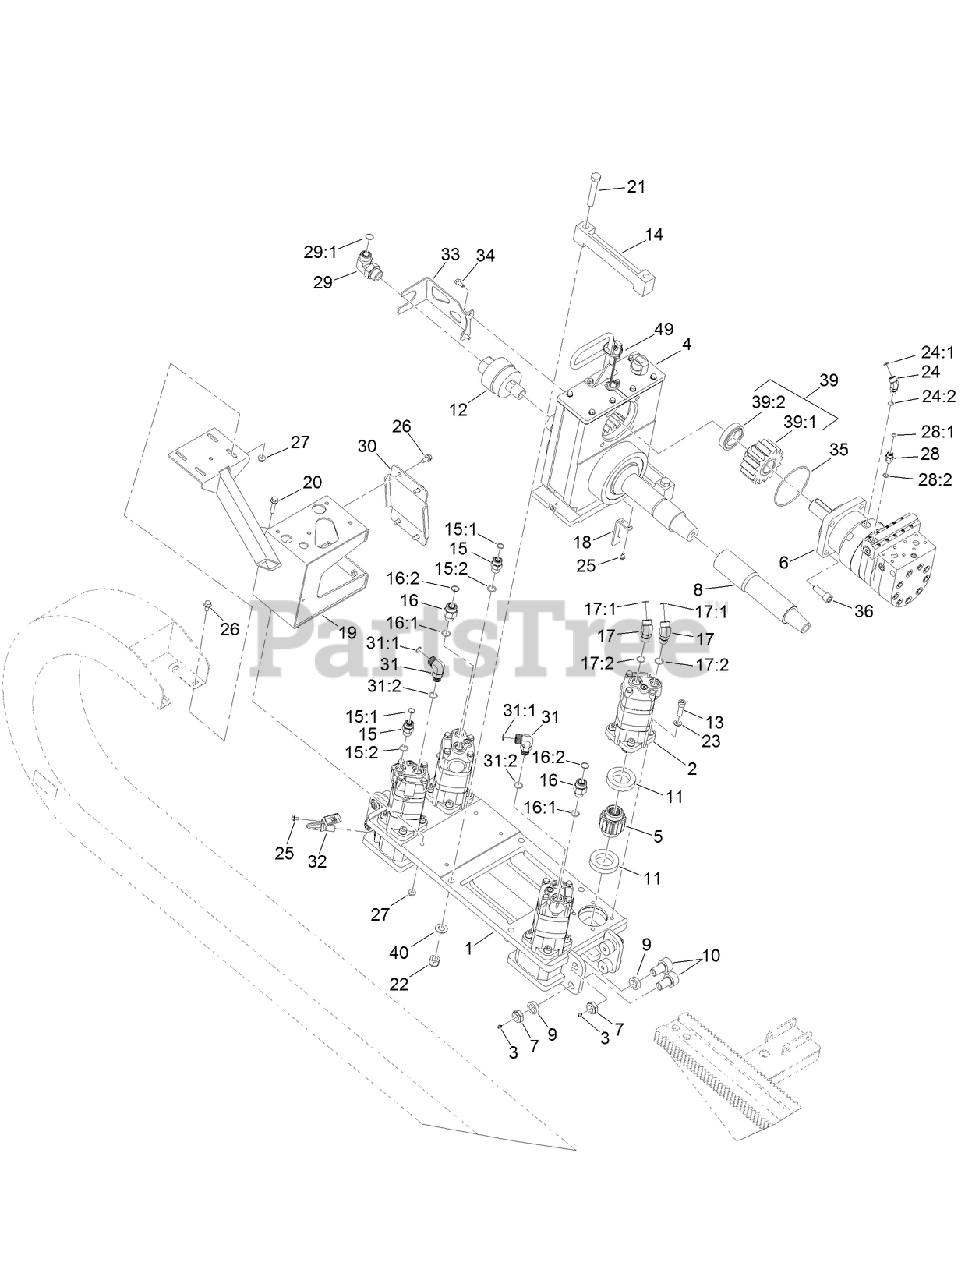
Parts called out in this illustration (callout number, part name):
2	MOTOR-THRUST
3	FITTING-GREASE, ZERK
4	ROTARY GEARBOX ASM
5	PINION-GEAR, THRUST
6	MOTOR ASM
8	SUBSAVER
9	SPACER-FOLLOWER, CAM
10	BEARING-ROLLER, CAM
11	BEARING-BALL, DOUBLE SEALED
12	SWIVEL-MUD
13	SCREW-HSH
14	PLATE-CLAMP
15	FITTING-STRAIGHT
15:1	O-RING
15:2	O-RING
16	FITTING-STRAIGHT
16:1	O-RING
16:2	O-RING
17	FITTING-HYD, 45 DEG
17:1	O-RING
17:2	O-RING
18	PLATE-FLAG
19	MOUNT-THRUST
20	SCREW-HHF
21	SCREW-HH
22	NUT-HEX
23	WASHER
24	ADAPTER
24:1	O-RING
24:2	O-RING
25	SCREW-HHF
27	NUT-HF, NI
28	FITTING-STRAIGHT
28:1	O-RING
28:2	O-RING
29:1	O-RING
30	PLATE-FRONT, THRUST MANIFOLD
31	FITTING-ELBOW, 90 DEG
31:1	O-RING
31:2	O-RING
32	SENSOR-GEARTOOTH
33	BRACKET-SWIVEL, MUD
34	SCREW-HHF
35	O-RING
36	SCREW-HSH
39	DRIVE MOTOR GEAR ASM
39:1	GEAR-PINION
39:2	BEARING
40	WASHER
49	TIE-CABLE
